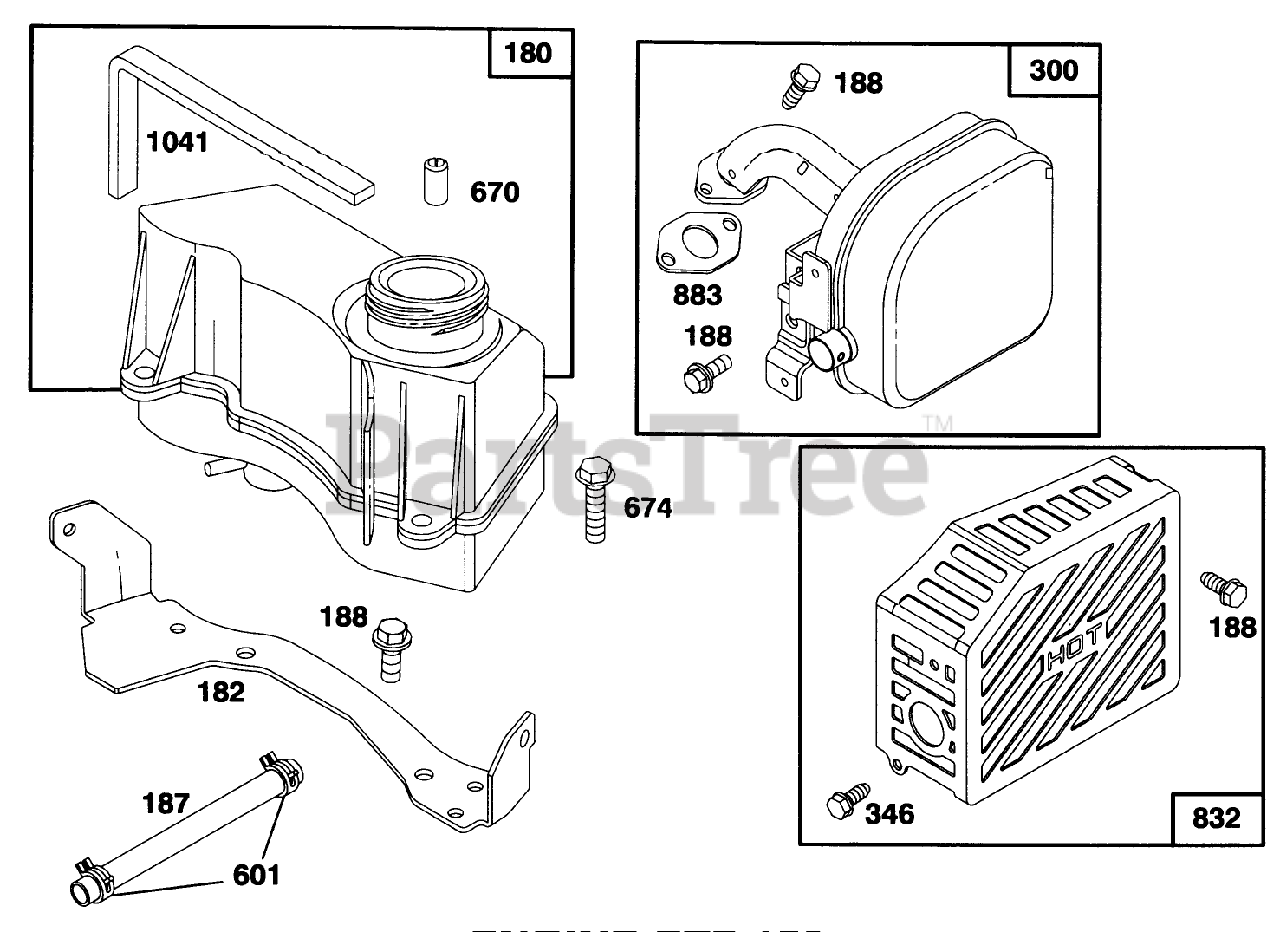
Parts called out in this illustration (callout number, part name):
180	TANK ASSY - FUEL
300	MUFFLER - EXHAUST
670	SPACER
674	SCREW - HEX HEAD
